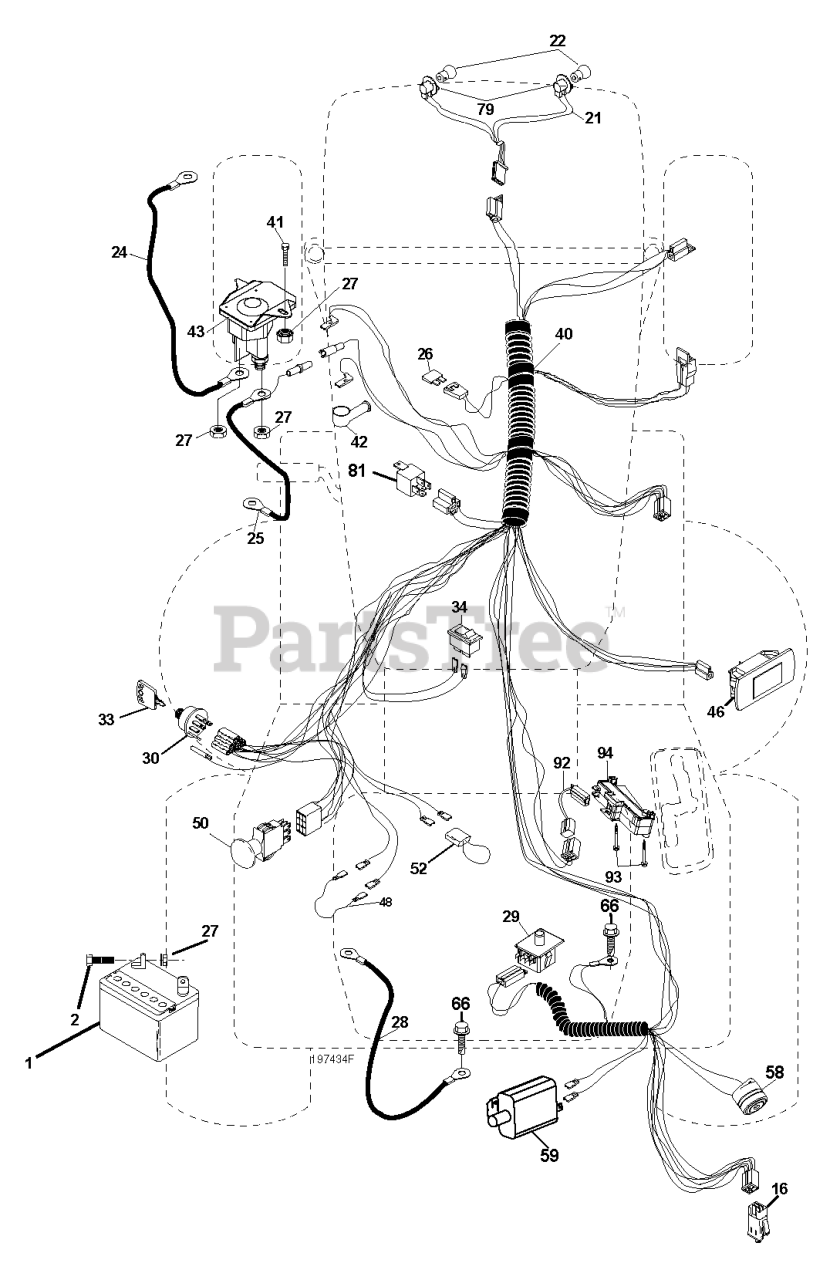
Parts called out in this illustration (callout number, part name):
1	BATTERY 12V .35 AMP
2	BOLT.HEX.1/4.X.3/4.DICHROMATE
16	SWITCH INTERLOOK PUSH-IN
21	HARNESS.LIGHT W/4152J BULBS
24	BATTERY CABLE GT
25	CABLE BATTERY
26	FUSE 20AMP
27	NUT
28	CABLE GROUND
29	SWITCH.SEAT.DP W/RAMPS
30	SWITCH.IGN.DELTA.W.LGH.ROS
33	KEY MLD GEN DELTA
40	RP HARNESS.IGN.ELECT.REG.CRD
41	BOLT
42	TERMINAL COVER
43	SOLENOID.W/BRASS.PLUNGER
46	PLUG DASH
48	ADAPTER.AMMETER
50	RP.PTO.SWITCH.8 TERMINAL.BLACK
52	WIRE PROTECTION LOOP
58	BUZZER
59	.WITCH.FULL BAGGER.INDICATOR
79	BULB HOLDER ASM.
81	RELAY.ASSY.T
92	HARNESS.PIGTAIL.CONSLE
93	SCREW.PLASTITE
94	MODULE.REVERSE.ROS
